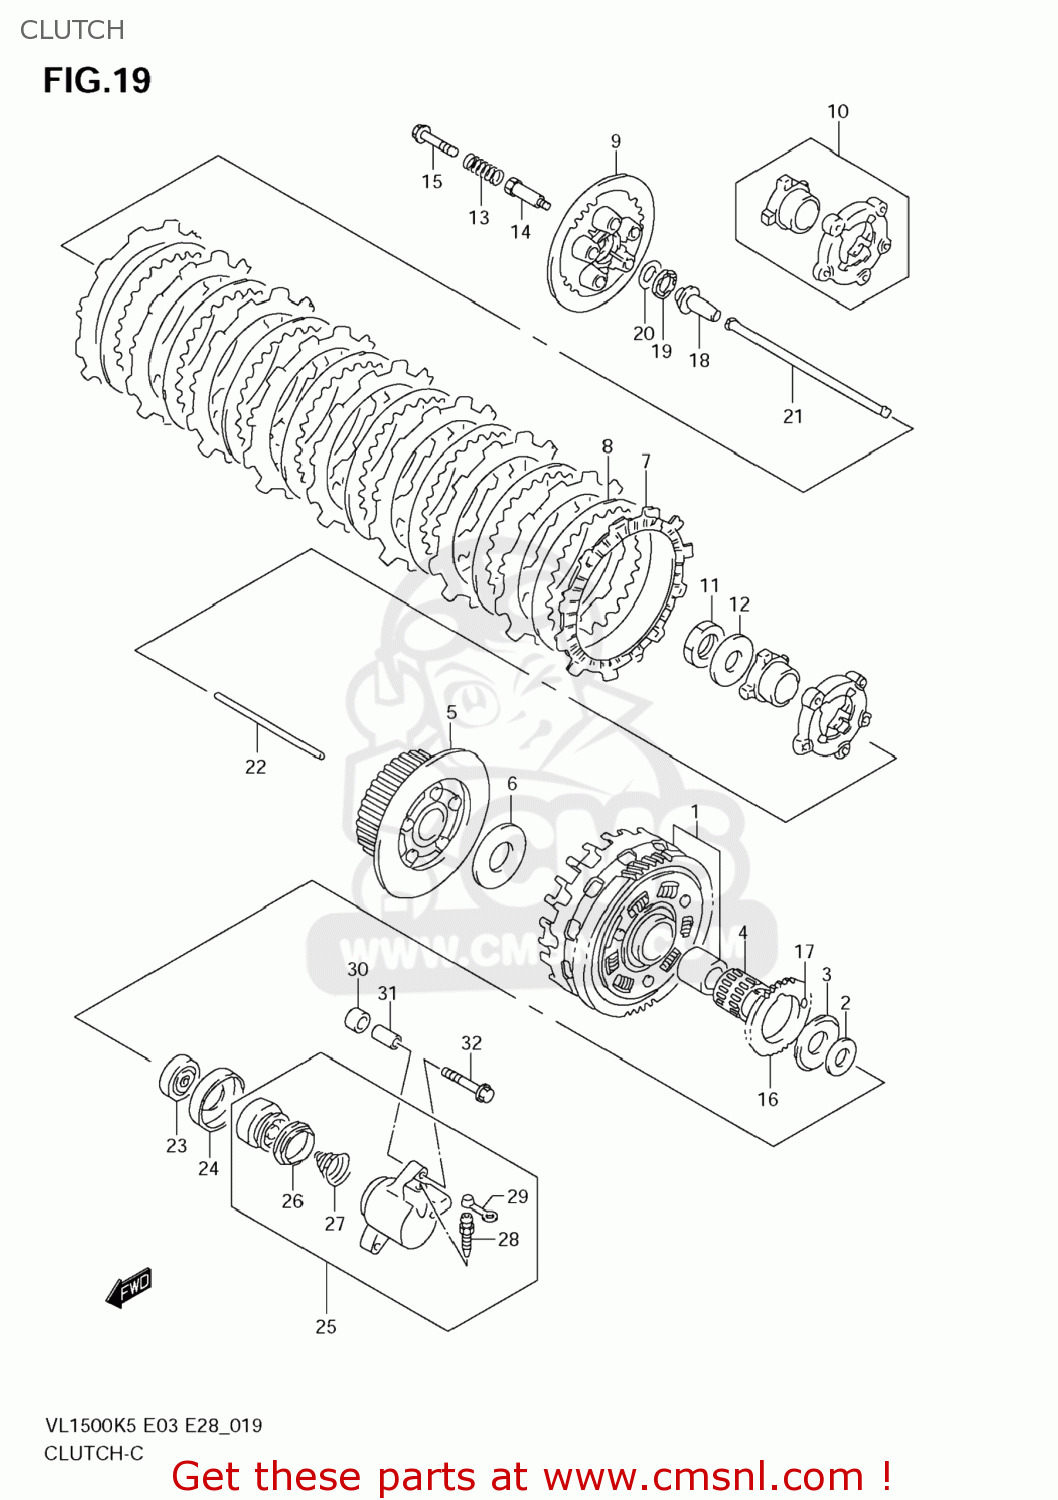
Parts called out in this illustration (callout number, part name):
1	GEAR ASSY,PRI DRIVEN
2	WASHER(25X38X2.5)
3	WASHER(25X54X2.5)
4	BEARING(35X40X35.8)
5	HUB,CLUTCH SLEEVE
6	WASHER(25X50X2.5)
7	PLATE,CLUTCH DRIVE (NAS)
8	PLATE,CLUTCH DRIVEN NO.1 (NAS)
9	DISC,CLUTCH PRESSURE
10	CAM SET,CLUTCH
11	NUT
12	WASHER
13	SPRING,CLUTCH
14	BOLT,CLUTCH SPRING SUPPORT
15	BOLT,CLUTCH SPRING
16	GEAR,OIL PUMP DRIVE
17	PIN(6X6)
18	PIECE,CLUTCH PUSH
19	BEARING(15X28X2)
20	WASHER(15.5X28X1)
21	ROD,CLUTCH PUSH,R
22	ROD,CLUTCH PUSH,L
23	SEAL,OIL(6X34X11)
24	RETAINER,CL PUSH ROD OIL SEAL
25	CYLINDER,CLUTCH RELEASE
26	CUP
27	SPRING
28	BLEEDER
29	CAP,BLEEDER
30	SPACER(9X16X11)
31	PIN(6.4X9X23)
32	BOLT
